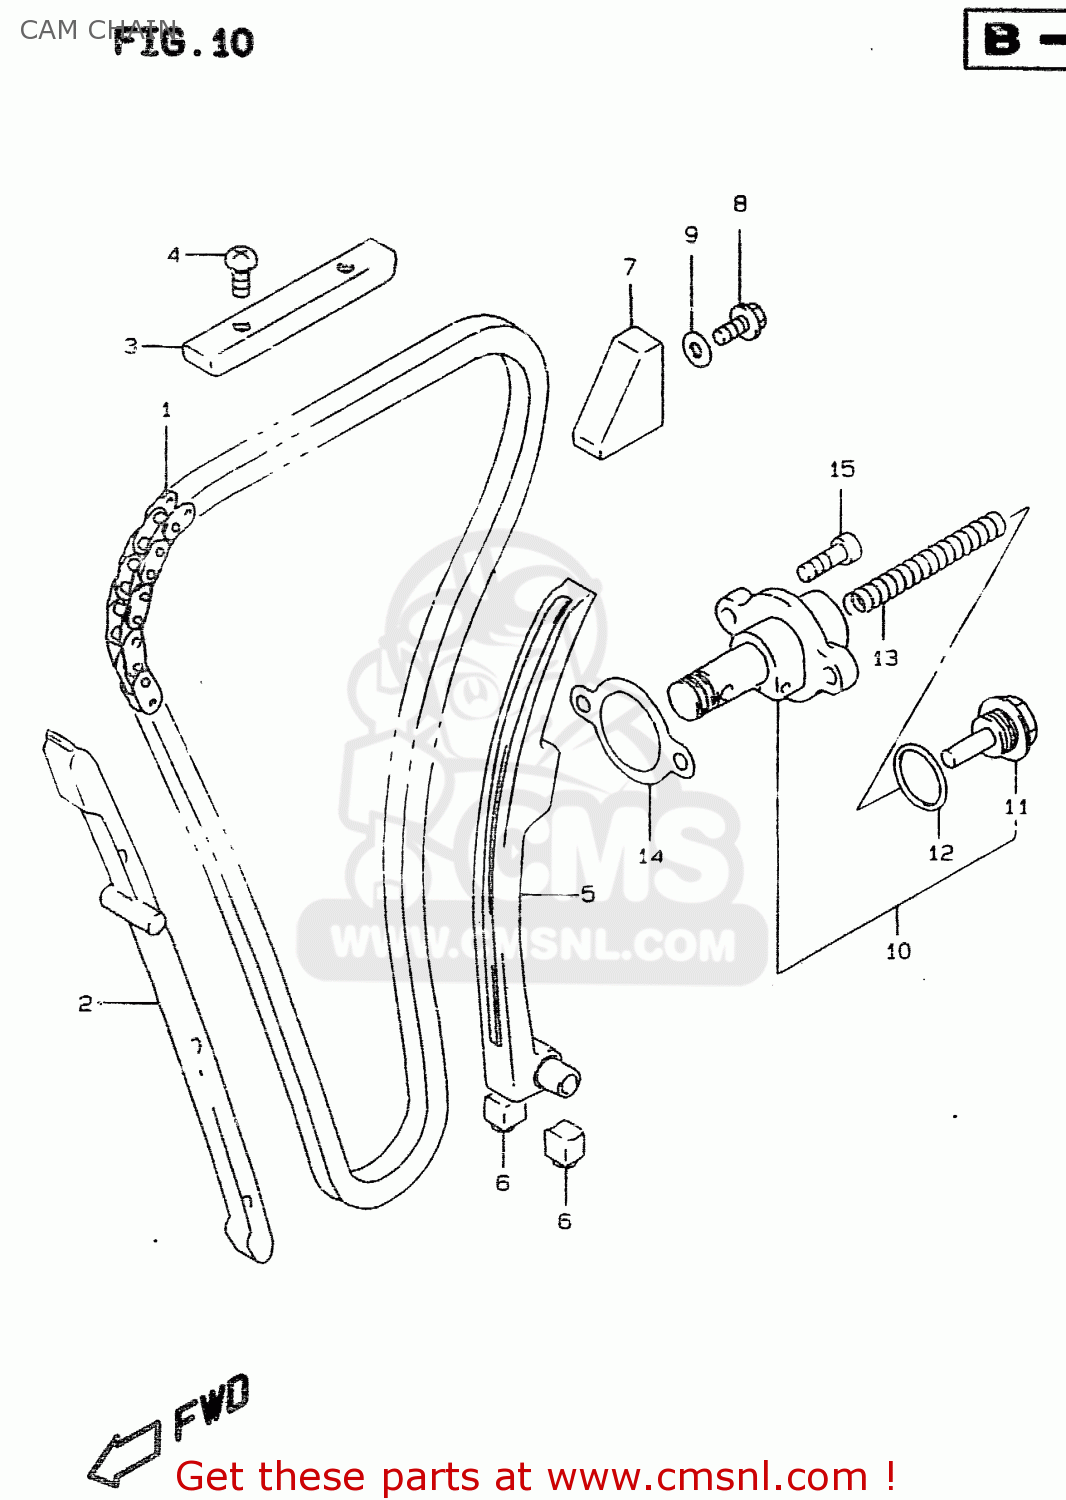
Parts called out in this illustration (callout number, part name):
1	CHAIN,CAMSHAFT DRIVE
2	GUIDE,CAM CAHIN NO.1
3	GUIDE,CAM CHAIN NO.2
4	SCREW
5	TENSIONER,CAM CHAIN
6	CUSHION,CAM CHAIN TENSIONER
7	GUIDE,CAM CHAIN NO.3
8	BOLT
9	GASKET(5.8X13X1.2) (NAS)
10	ADJUSTER ASSY,TENSIONER
11	PLUG
12	GASKET (NAS)
13	SPRING
14	GASKET,TENSIONER ADJUSTER (NAS)
15	BOLT
